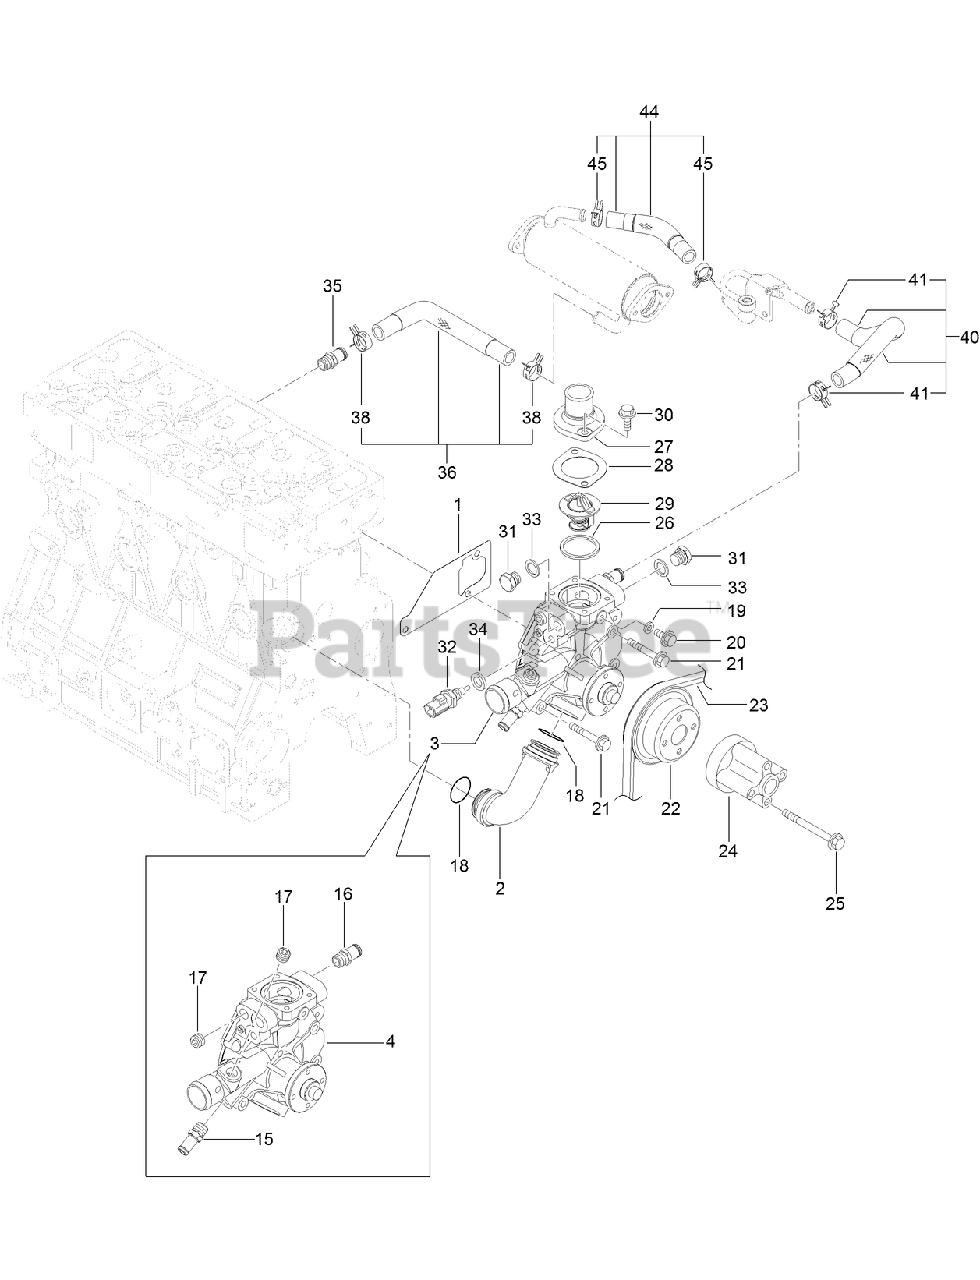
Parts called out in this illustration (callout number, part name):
1	GASKET-PUMP, WATER
2	PIPE-WATER
3	WATER PUMP ASM
4	WATER PUMP ASM
18	O-RING
19	GASKET
22	PULLEY-FAN
23	BELT-V
24	SPACER-FAN
26	GASKET-THERMOSTAT
27	COVER-THERMOSTAT
28	GASKET-COVER, THERMOSTAT
29	THERMOSTAT
32	SENSOR-THERMOSTAT, CW
33	GASKET
34	WASHER-SEAL
36	E G R-C IN HOSE ASM
38	CLIP-HOSE
40	E G R- C OUT B HOSE ASM
41	CLIP-HOSE
44	E G R- C OUT A HOSE ASM
45	CLIP-HOSE
